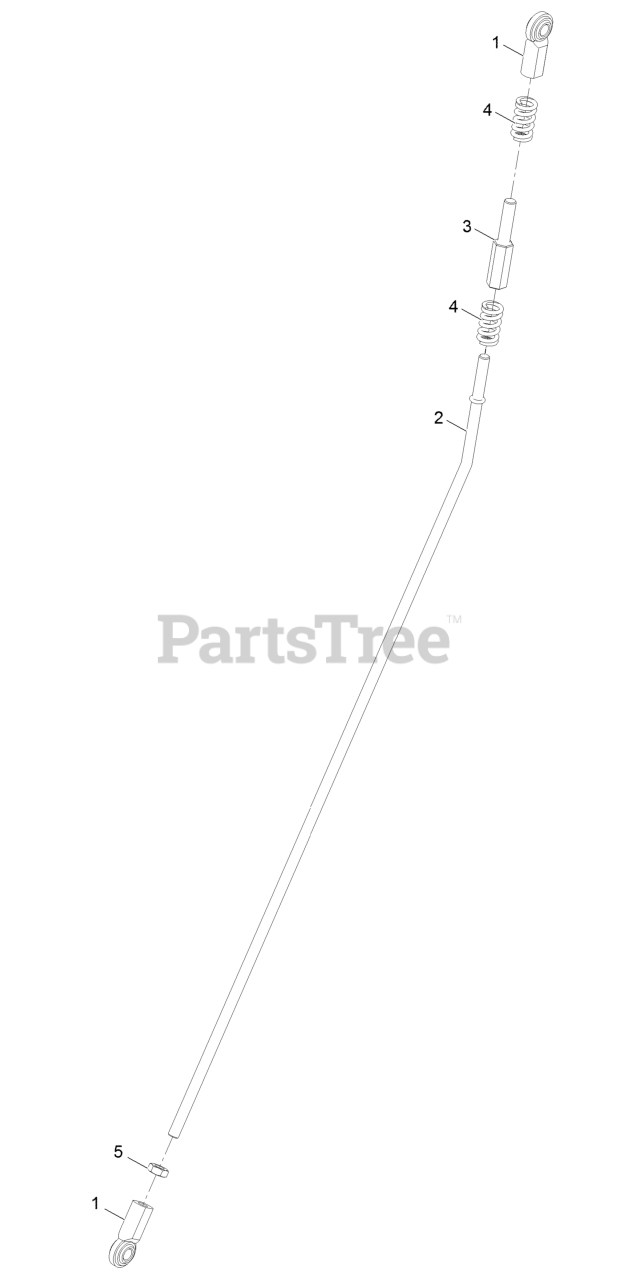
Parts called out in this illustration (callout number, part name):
1	Balljoint
2	Linkage-Motion
3	Rod-Adjustment
4	Spring-Compression
5	Nut-Jam 3/8-24
